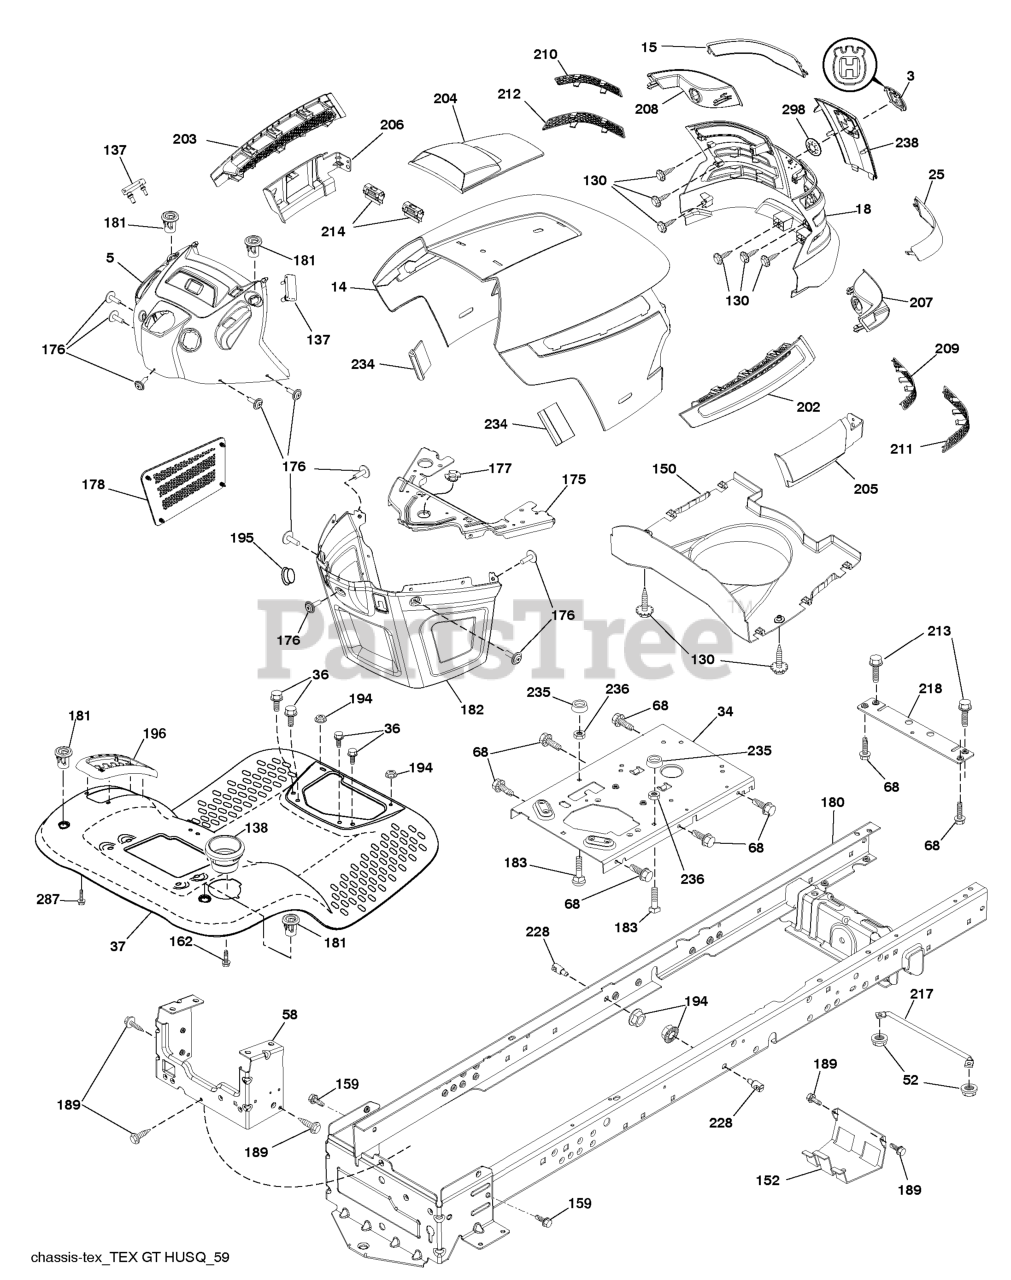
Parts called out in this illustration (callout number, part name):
3	LOGO.HUSQ.GT.LT.CROWN.H
14	HOOD
15	LENS.LH.TEX.GT.HUSQ.CL
18	GRILL.ASM.HUSQ.TG/CRD.W/TRIM
25	LENS.RH.TEX.GT.HUSQ.CL
34	PLATE.ENGINE.WELDED.CHASSIS
36	SCREW 5/16"
37	FENDER
52	LOCKNUT
58	DRAWBAR UPPER 2PC SMALL FENDER
68	Screw Thdrol 5/16-18 x 1/2
130	SCREW.#10 X 0.750.BOS
137	BUMPER DASH
138	CUPHOLDER.TL.TEX.418
150	AIR.DUCT.TEXGT.HUSQ.SV
152	SHIELD.BROWNING.W/TEX
159	SCREW, 3/8-16X3/4
162	SCREW.HI-LO.CONSOLE
175	PLATE.CROSSMEMBER.HUSQ
176	SCREW.#10-24X5/8.RN.QU
177	BUSHING, STEERING
178	CARGO.ASM.NET.TXGT.W/C
180	CHASS.WLDMNT.TL.12GA/2P.48/54
181	BUSHING.MNT.FEND.CRGO.
182	DASH.LOWER.COMMON.12V.ADAPTOR
183	BOLT.5/16-18X1-1/4 FULL THD
189	SCREW
194	NUT LOCK HEX FLANGE 5/16-18
195	PLUG.HOLE.DASH.LOWER.12V.BLK
196	RP CONSOLE.ASM.DECKLFT.GR/RBT.
202	VENT.SIDE.HOOD.HUSQ.RH.GREY
203	VENT.SIDE.HOOD.HUSQ.LH.GRAY
204	HOOD VENT
205	SKIRT.HOOD.SIDE.HUSQ.RH.GREY
206	SKIRT.HOOD.SIDE.HUSQ.LH.GREY
207	BEZEL.RH.TEX.GT.HUSQ
208	BEZEL.LH.TEX.GT.HUSQ
209	INSERT.HEX.GRILL.HUSQ.GREY
210	INSERT.HEX.GRILL.HUSQ.
211	INSERT.HEX.GRILL.HUSQ.
212	INSERT.HEX.GRILL.HUSQ.
213	BOLT
214	CLIP.RETAINER.TINNER.
217	ROD.PIVOT.HOOD
218	X-PIECE.HOOD.STOP.NON/
228	STUD.FASTNER.W/ANTI-ROTATE
234	BUMPER.HOOD.TEX.HUSQVARNA
235	SPACER FENDER
236	NUT.CENTERLOCK.5/16-
238	TRIM.HUSQ.TG/CRD.SERVICE
287	SCREW 1/4X20
298	NUT PUSH M
